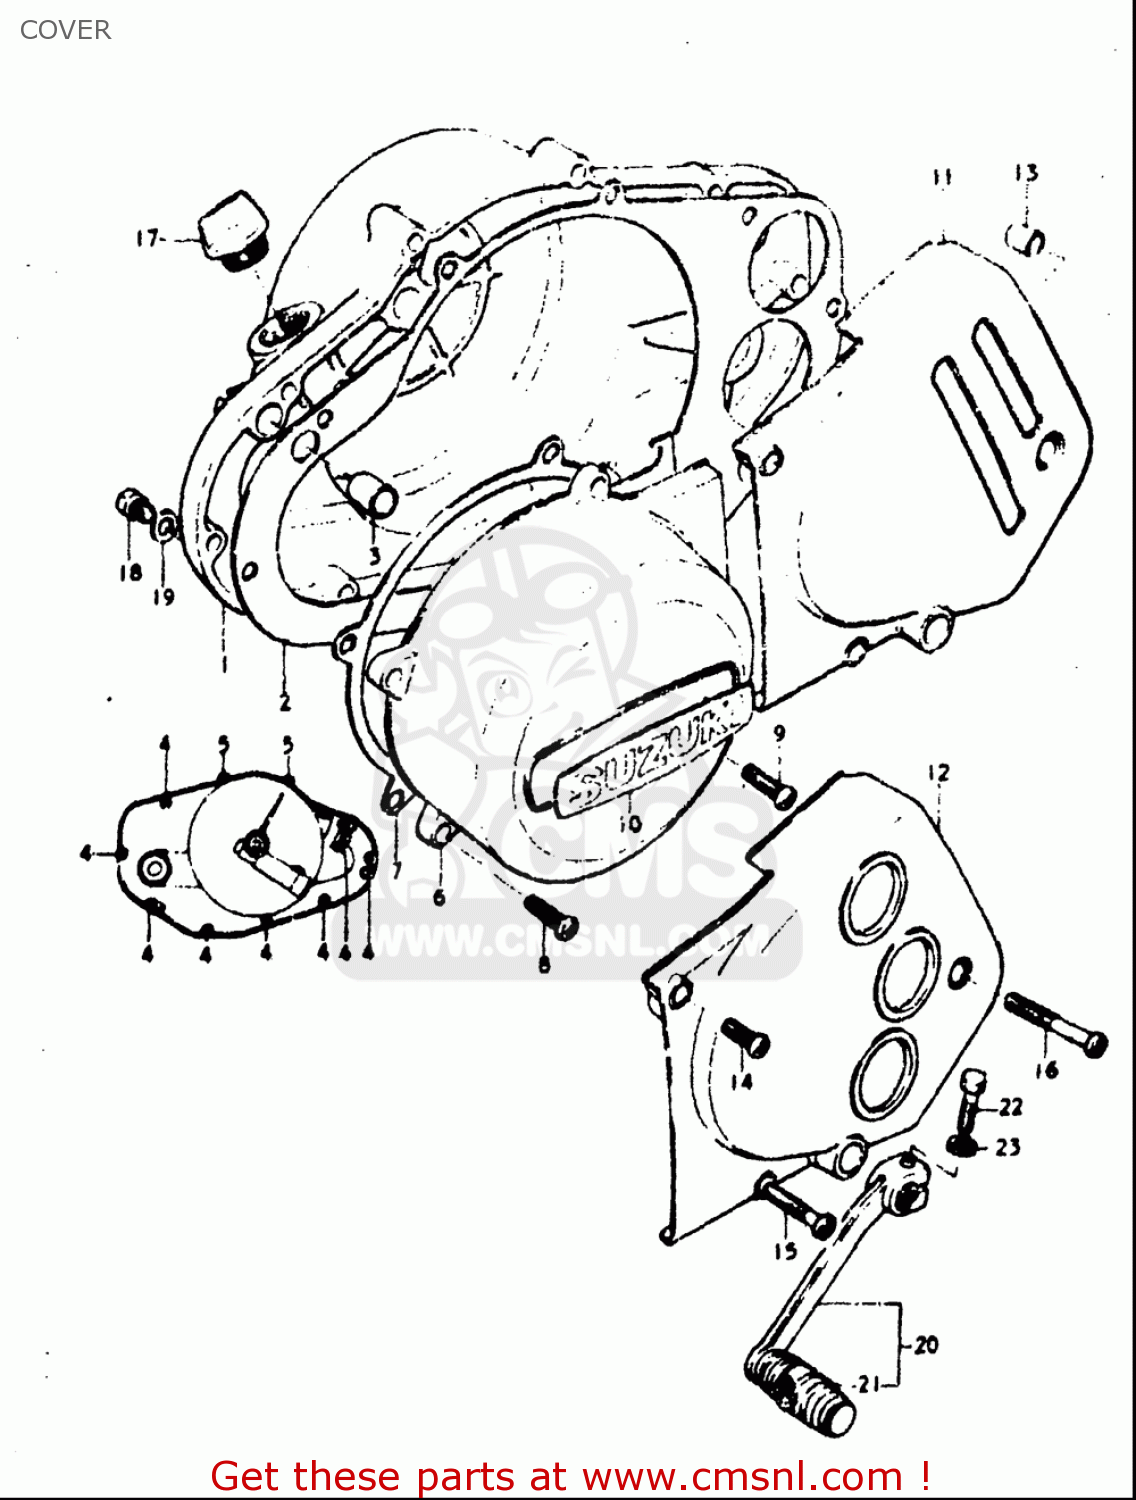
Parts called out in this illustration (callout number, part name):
3	PIN
4	SCREW
5	SCREW
8	SCREW
9	SCREW
13	PIN
14	SCREW
15	SCREW
16	SCREW
17	PLUG SET
18	SCREW(6X10)
19	GASKET(6.2X11X1) (NAS)
20	LEVER ASSY,GEAR SHIFT
21	RUBBER,GEAR SHIFT PEDAL
22	BOLT
23	WASHER,LOCK
